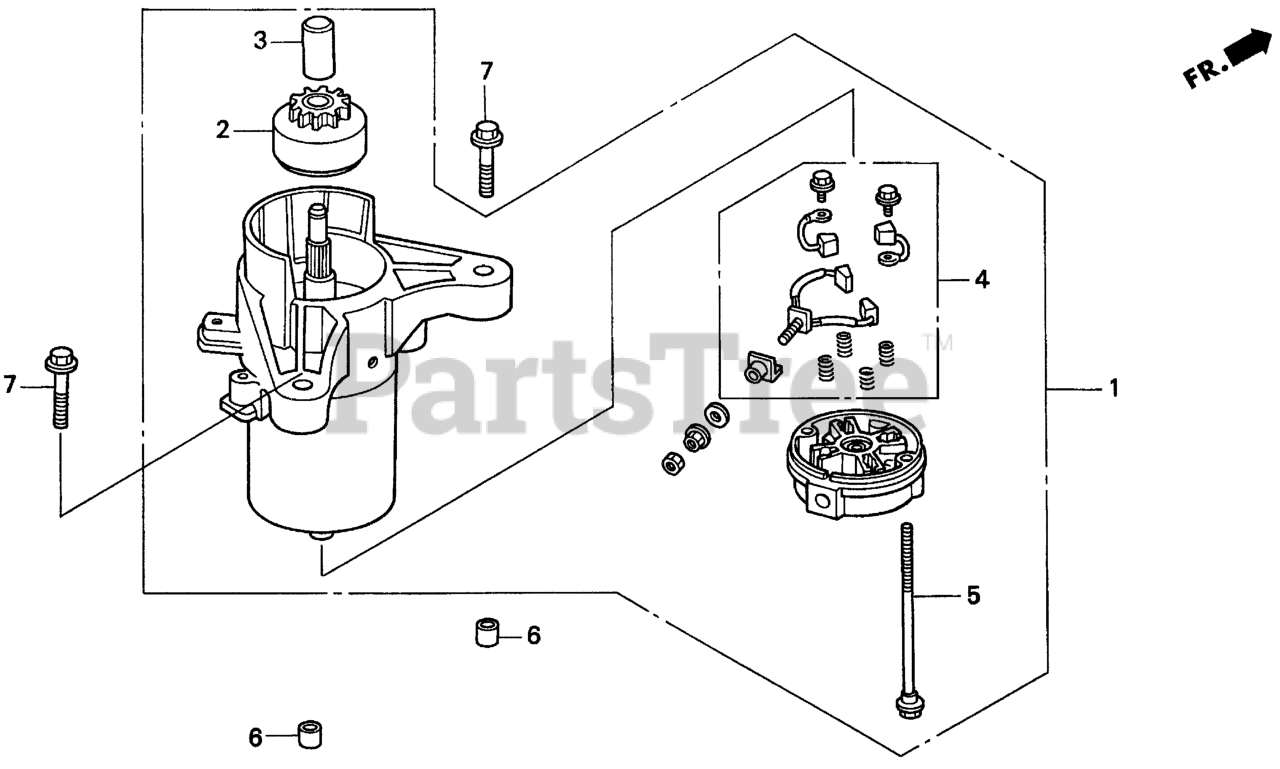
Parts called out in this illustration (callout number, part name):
1	MOTOR ASSY., STARTER
2	DRIVE ASSY.
3	STOPPER SET, PINION
4	BRUSH SET
5	BOLT, THROUGH
6	PIN, DOWEL (10X12)
7	BOLT, FLANGE (8X35)
